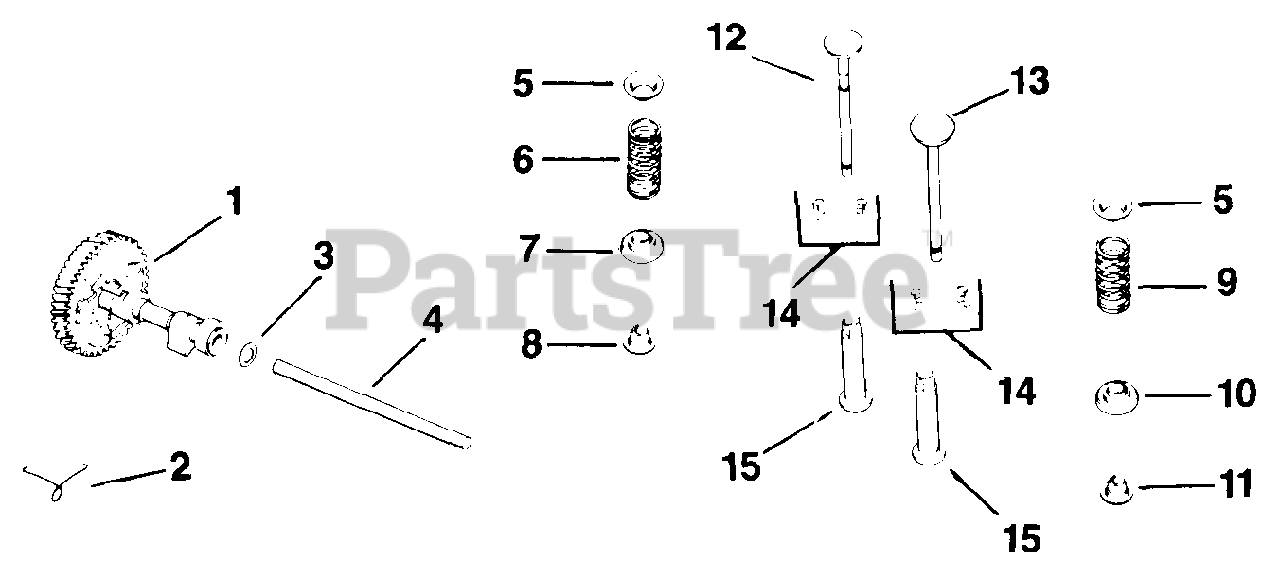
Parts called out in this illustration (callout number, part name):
1	CAMSHAFT
2	SPRING, ACTUATING-DISCONTINUED
3	SPACER (.005")
3	SPACER (.010")
4	PIN, CAMSHAFT - DISCONTINUED
5	RETAINER, SPRING
6	SPRING, INTAKE VALVE
9	SPRING, INTAKE VALVE
12	VALVE, EXHAUST
14	KIT, RETAINER
